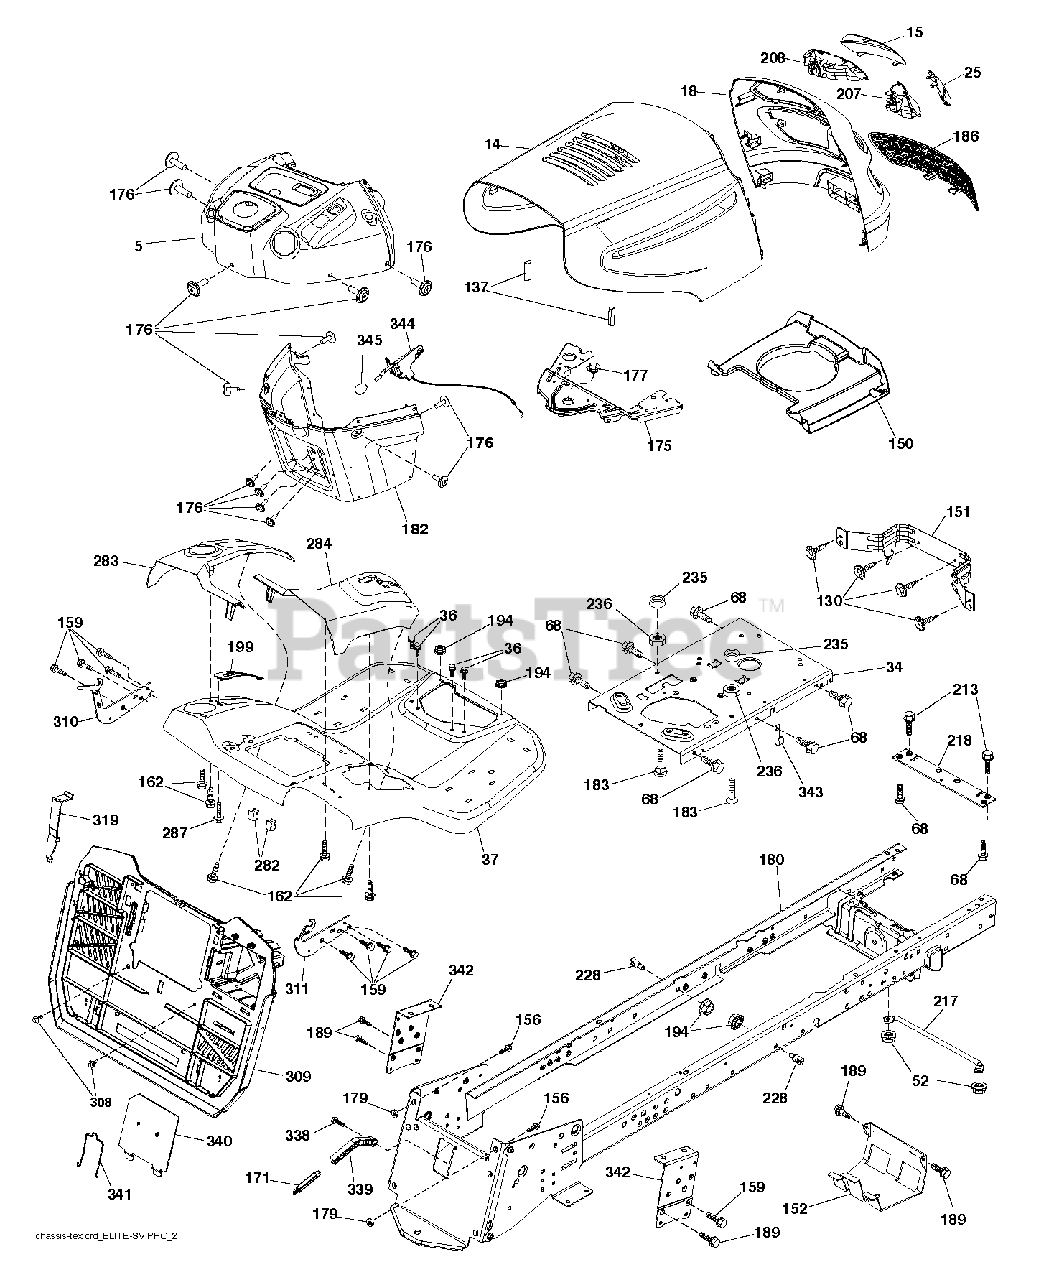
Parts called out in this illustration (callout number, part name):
36	SCREW 5/16"
52	LOCKNUT
130	SCREW.#10 X 0.750.BOS THREAD
137	BUMPER.HOOD.LARGE.1.75"
151	BRACKET PIVOT
152	SHIELD BROWNING
156	BOLT
159	SCREW, 3/8-16X3/4
162	SCREW.HI-LO.CONSOLE
175	CROSSMEMBER.LT
176	SCREW.#10-24X5/8.RN.QU
177	BUSHING STEERING
183	BOLT.5/16-18X1-1/4 FULL THD
189	SCREW
194	NUT LOCK HEX FLANGE 5/16-18
207	BEZEL GRILL RH
208	BEZEL GRILL LH
213	BOLT
217	ROD.PIVOT.HOOD
218	X-PIECE.HOOD.STOP.NON/
228	STUD.FASTNER.W/ANTI-ROTATE
235	SPACER FENDER
236	NUT.CENTERLOCK.5/16-
282	CLIP.RETAINER.CONSOLE.LT.HUSQ
308	BOLT, 5/16-18 X 1 3/4
